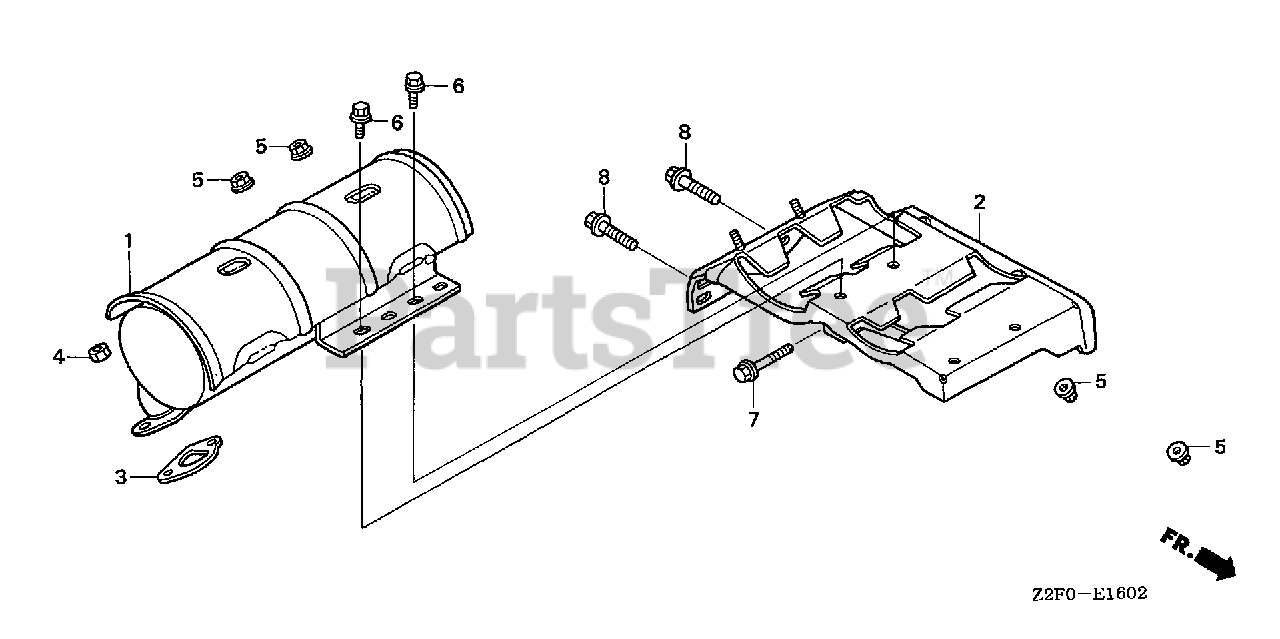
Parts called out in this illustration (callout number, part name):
2	STAY, MUFFLER
3	GASKET, MUFFLER
4	NUT, HEX. (8MM)
5	NUT, FLANGE (6MM)
6	BOLT, FLANGE (6X16)
7	BOLT, FLANGE (6X25)
8	BOLT, FLANGE (8X20)
